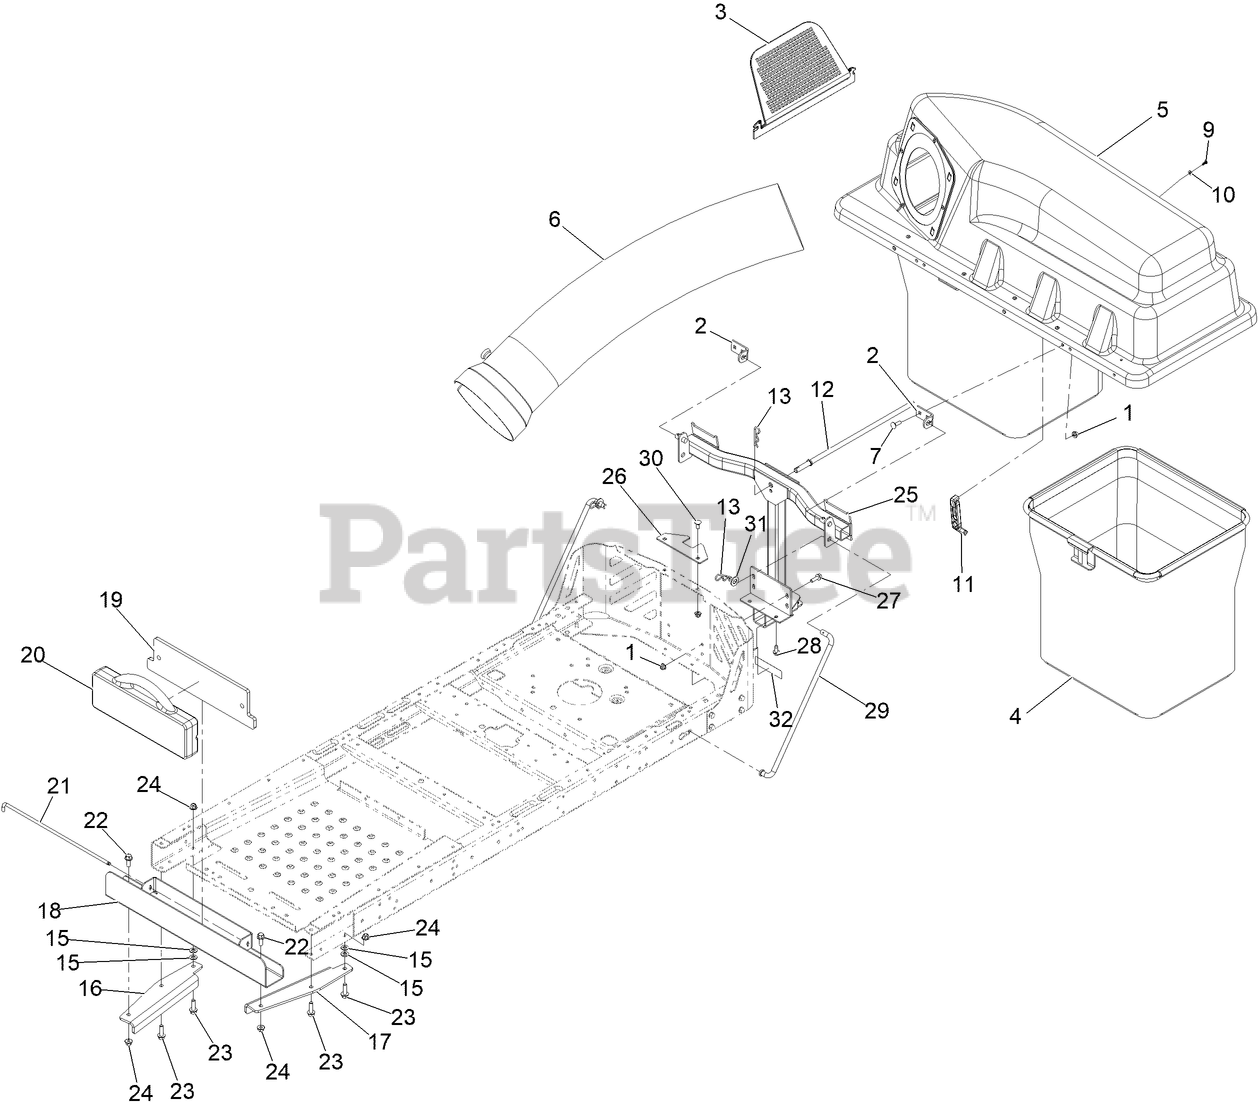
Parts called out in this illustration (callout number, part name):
1	NUT-HF, NI
2	BRACKET-PIVOT, HOPPER
3	SCREEN-BAGGER
4	BAG ASM
5	BAGGER TOP ASM
6	TUBE-BAGGER
7	BOLT-CARR
9	SCREW-PLASTIC, PTH
10	WASHER-FLAT
11	LATCH-RUBBER
12	ROD-HOOD, DOWN (HOLD)
13	PIN-HAIR
15	WASHER-FLAT
17	BRACKET-BAGGER WEIGHT, LH
18	CHANNEL-WEIGHT, BAGGER
20	WEIGHT-35 POUND
21	PIN-WEIGHT
22	SCREW-HHF 3/8-16 X 1
23	SCREW-HHF
24	NUT-HF, NI
25	Frame ASM, Pivot [black]
26	BRACKET-STABILIZER
27	SCREW-HHF
28	Screw-HWH 5/16-18 X 3/4 Tf
29	ROD-SUPPORT
30	BOLT-CARR
31	WASHER-FLAT
